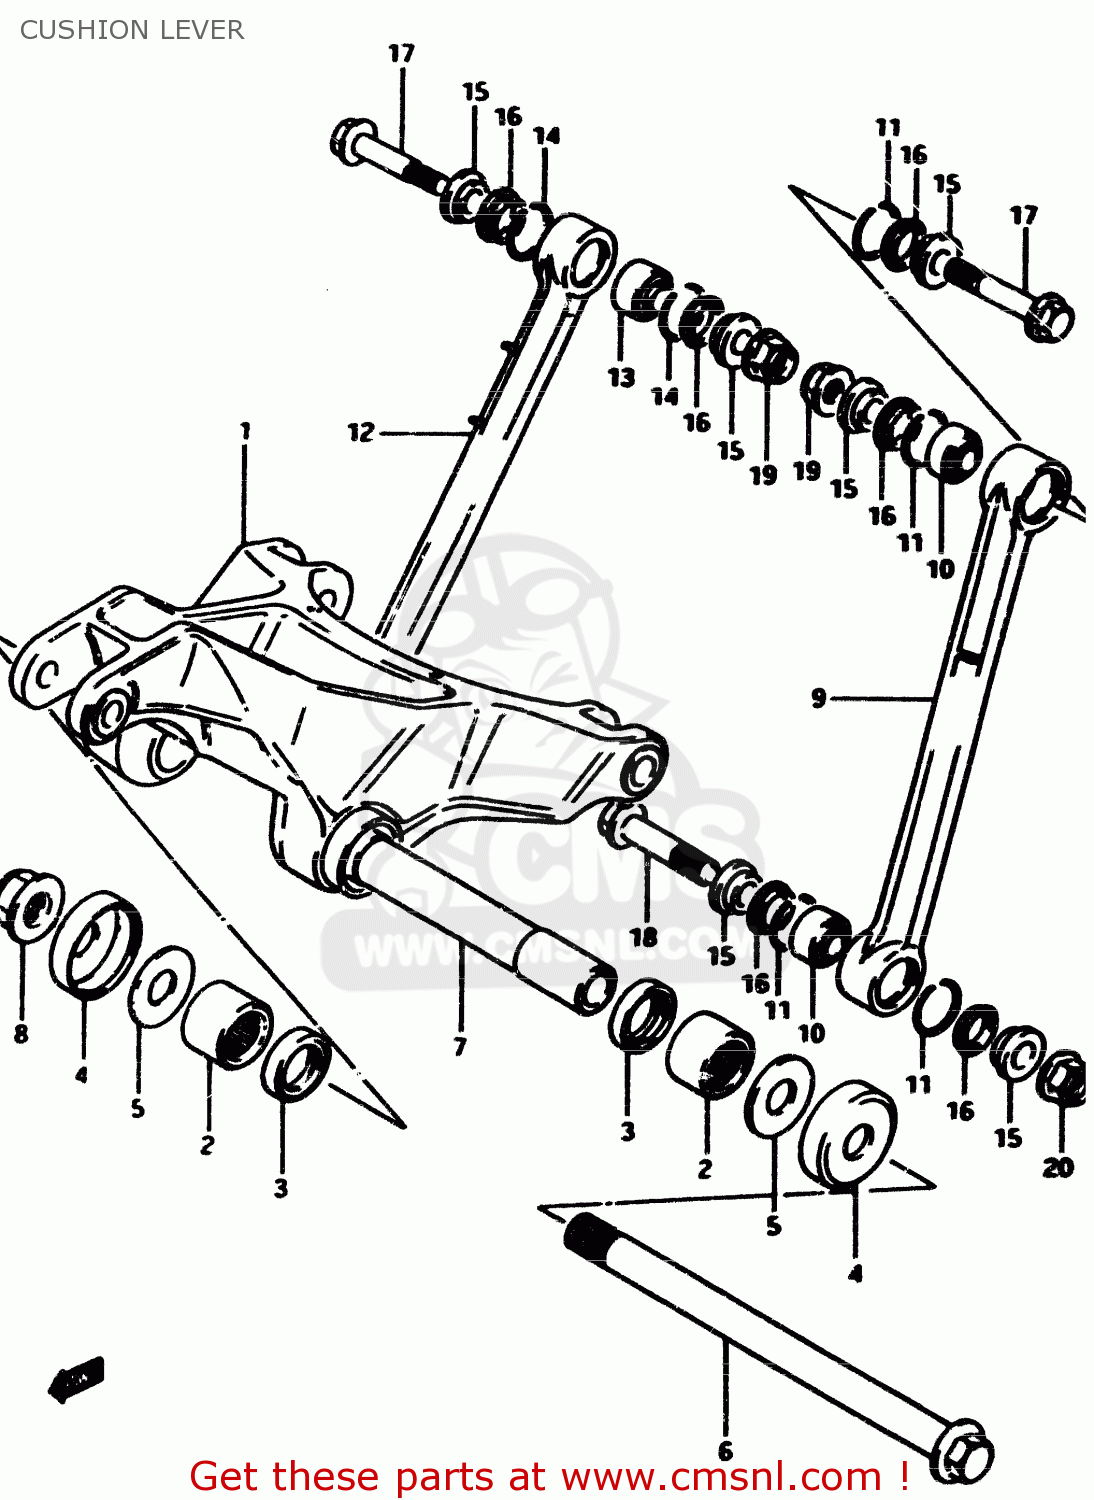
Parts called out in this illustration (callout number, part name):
1	LEVER SET,REAR CUSHION
2	BEARING(20X27X25)
3	SEAL,CUSHION LEVER DUST
4	CVR,RR SWGARM DUST SEAL(OD:40)
5	WASHER
6	SHAFT,REAR CUSHION LEVER
7	SPACER,REAR CUSHION LEVER
8	NUT
9	LEVER SET,REAR CUSHION
10	BEARING(10X21X13)
11	RING,BEARING STOPPER
12	LEVER SET,REAR CUSHION
13	BEARING(10X21X13)
14	RING,BEARING STOPPER
15	SPACER,REAR CUSHION ROD
16	DUST SEAL,RR CUSHION ROD
17	BOLT,REAR CUSHION ROD
18	BOLT,RR CUSHION ROD LWR
19	NUT
20	NUT
